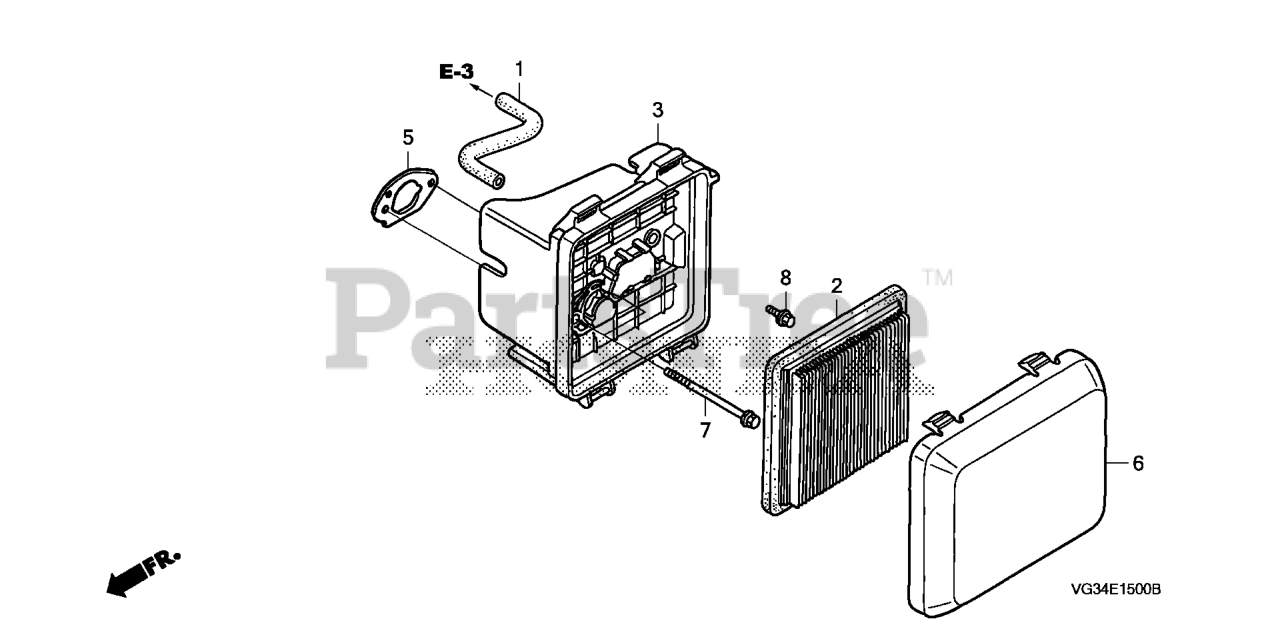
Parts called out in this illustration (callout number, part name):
1	TUBE, BREATHER
2	ELEMENT, AIR CLEANER (WIX FILTERS)
3	HOUSING, AIR CLEANER
5	GASKET, AIR CLEANER
6	COVER, AIR CLEANER
7	BOLT, SPECIAL (6MM)
